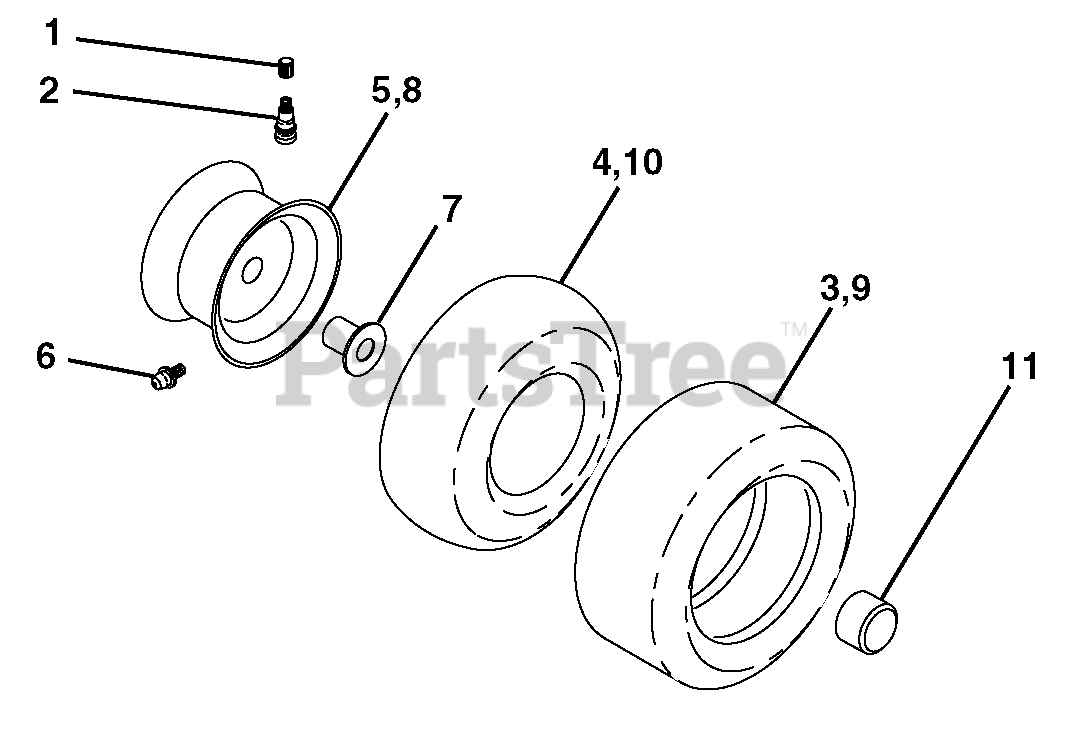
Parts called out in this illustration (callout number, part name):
1	Cap Valve Tire
2	Stem Valve
3	Tire F T 15 x 6 0 - 6
4	Tube Front
5	Rim Asm 6" Front
6	Fitting Grease
7	Bearing Flange
8	Rim Asm 8" Rear
9	Tire R 18 x 9.5-8 Turf Saver
9	Tire R 18 x 9.5-8 Turf Saver LT
10	Tube Rear
11	Cap Axle
11	Sealant, Tire ( 10 oz. Tube)
